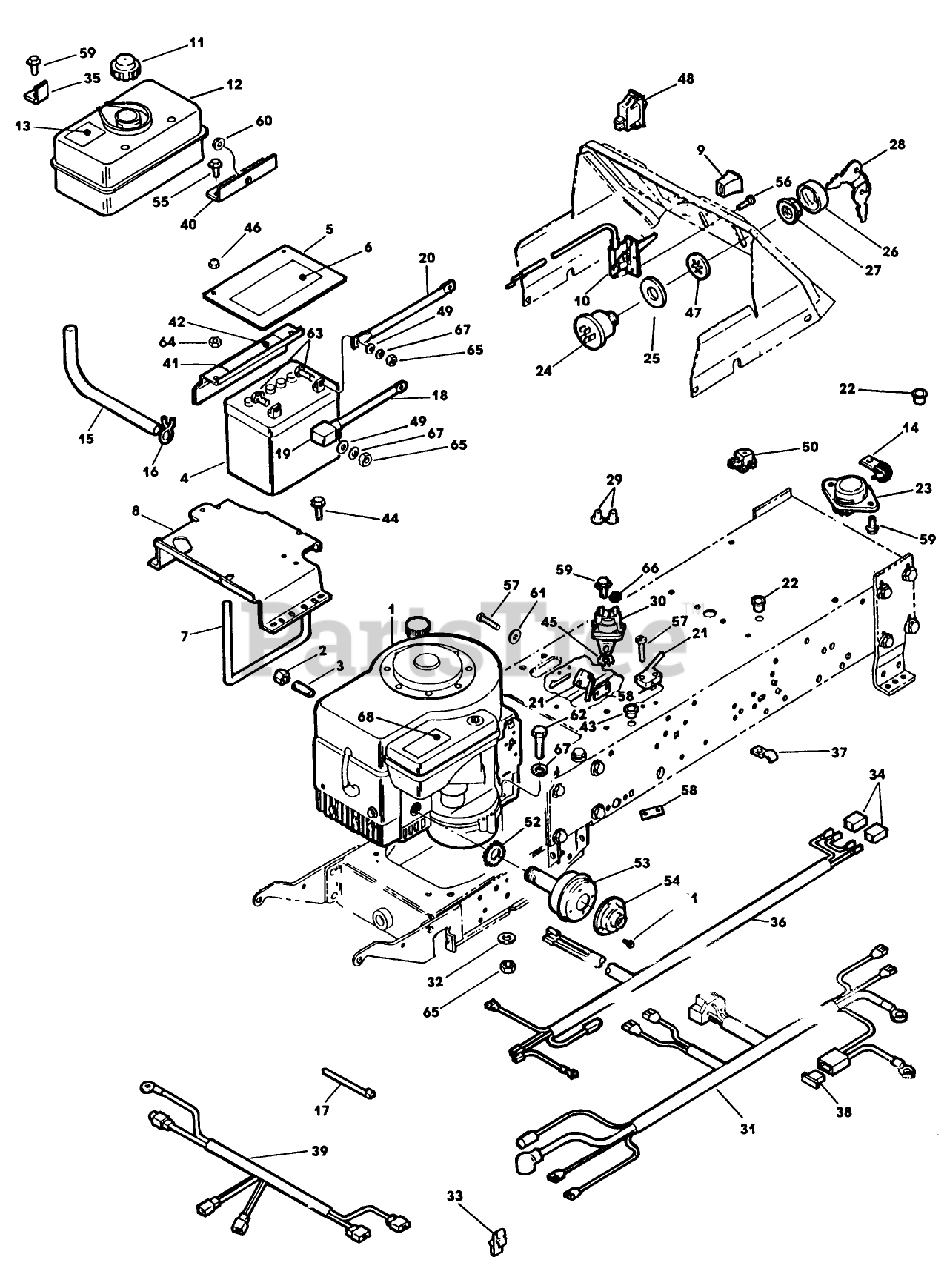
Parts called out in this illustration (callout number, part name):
5	BATT. CVR & R/B 744648
9	THROTTLE KNOB
11	CAP-FUEL
12	TANK & STICKER AY
18	CABLE ASSEMBLY
23	SWITCH,SEAT
30	SOLENOID
46	NUT-LOCK, CONE
48	SWITCH ASSEMBLY
63	SCREW - HEX
66	NUT-HEX
